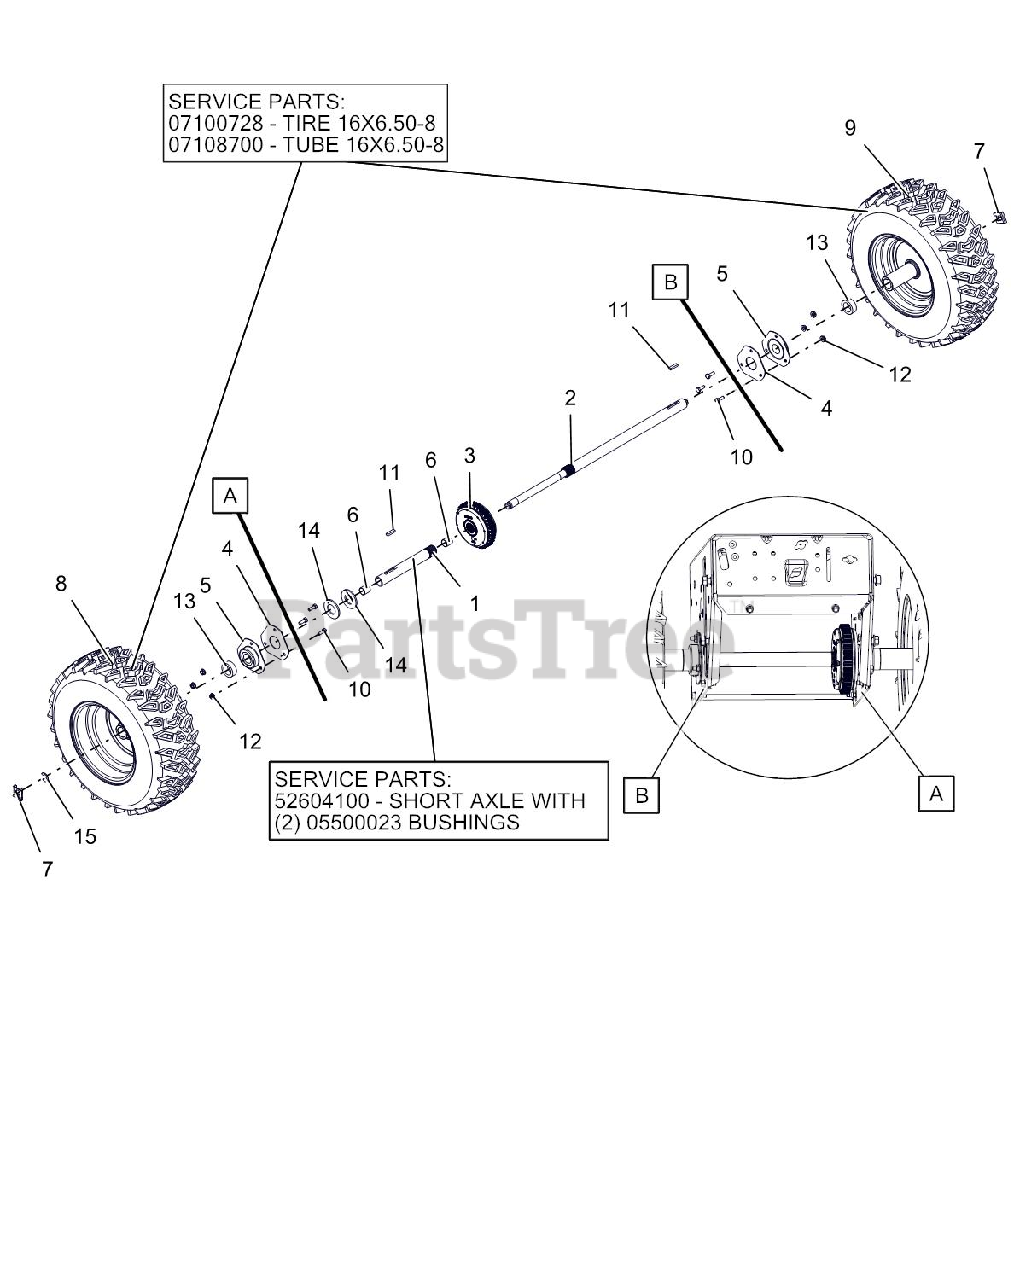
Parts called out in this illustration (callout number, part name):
1	BSHG-SLV .706X.764X.75 BRZ
1	AXLE, SHORT-PRO AUTO DIFF
1	AXLE, SHORT-AUTO W/BUSHINGS
2	AXLE, LONG-PRO AUTO DIFF
3	DIFFERENTIAL, AUTOMATIC
4	PLATE, BEARING SPACER
5	BRG-FLG 1.003/1.000 3 BOLT
6	BSHG-SLV .706X.764X.75 BRZ
7	CLIP, SNAP .625 DIA
8	TIRE/WHEEL,RH 16X6.5-8 DIFF T2
9	TIRE/WHEEL,LH 16X6.5-8 DIFF T2
10	@BLT-HEX .25-20X.75 GR5 YWZC
11	KEY-RECT .25X.188X1.00
12	@NUT-LK-CTR-FLG .25-20 YWZC
13	SPACER, PRO AXLE BEARING
14	WSHR-FL-STL- 1.062X2.0X.134 YZ
15	RG-RTNG-EXT .625X.042
16	TIRE, 16X6.50-8 K478
17	TUBE
